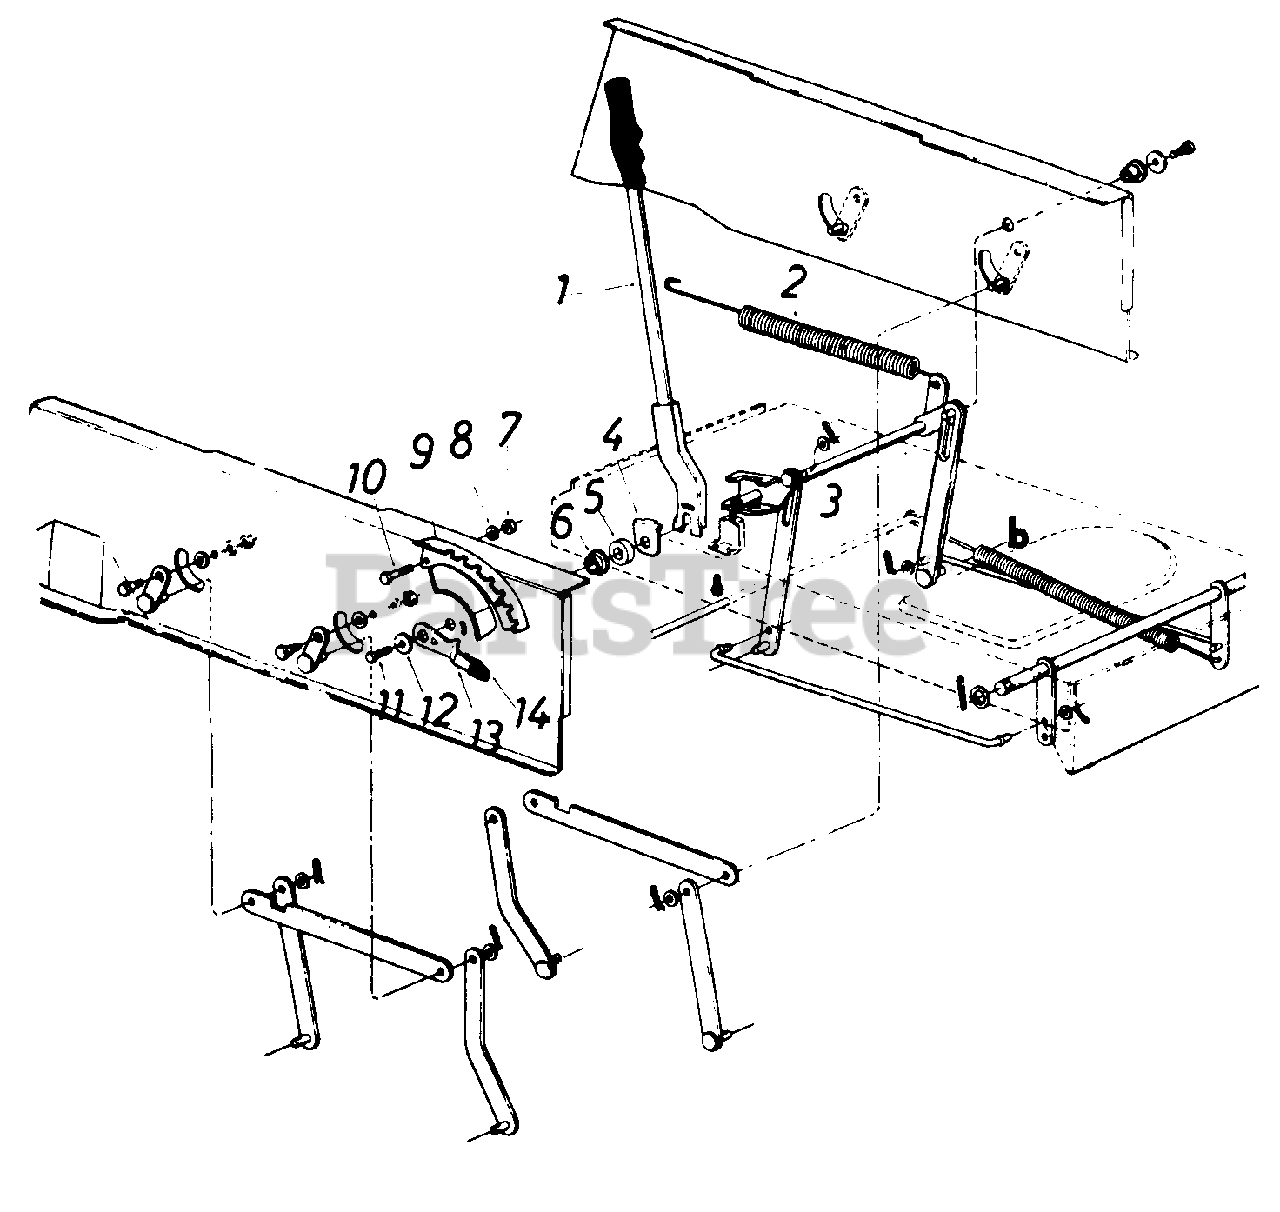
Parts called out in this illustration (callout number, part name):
1	Lift Handle P ss'y.
2	Extension Spring .99" O.D. x 11" Lg.
5	Rubber Wash. 1.50" O.D. x .63" I.D.
6	Flange Wash. .628" I.D. x 1.25" O. D
7	Hex Nut 5/16-18 Thcl.
8	L.Wash.5/16" I.D.
9	Index Eracket
10	Hex Bolt 5/16-18 x .75" Lg.
11	Hex Wash. Hd. Self-Tap Scr. 5/16-18 x .62" Lg.
12	Fl.-Wash. .344" I.D. x 1.25" Lg.
13	Deck Lift-Down Stop
14	Knob
